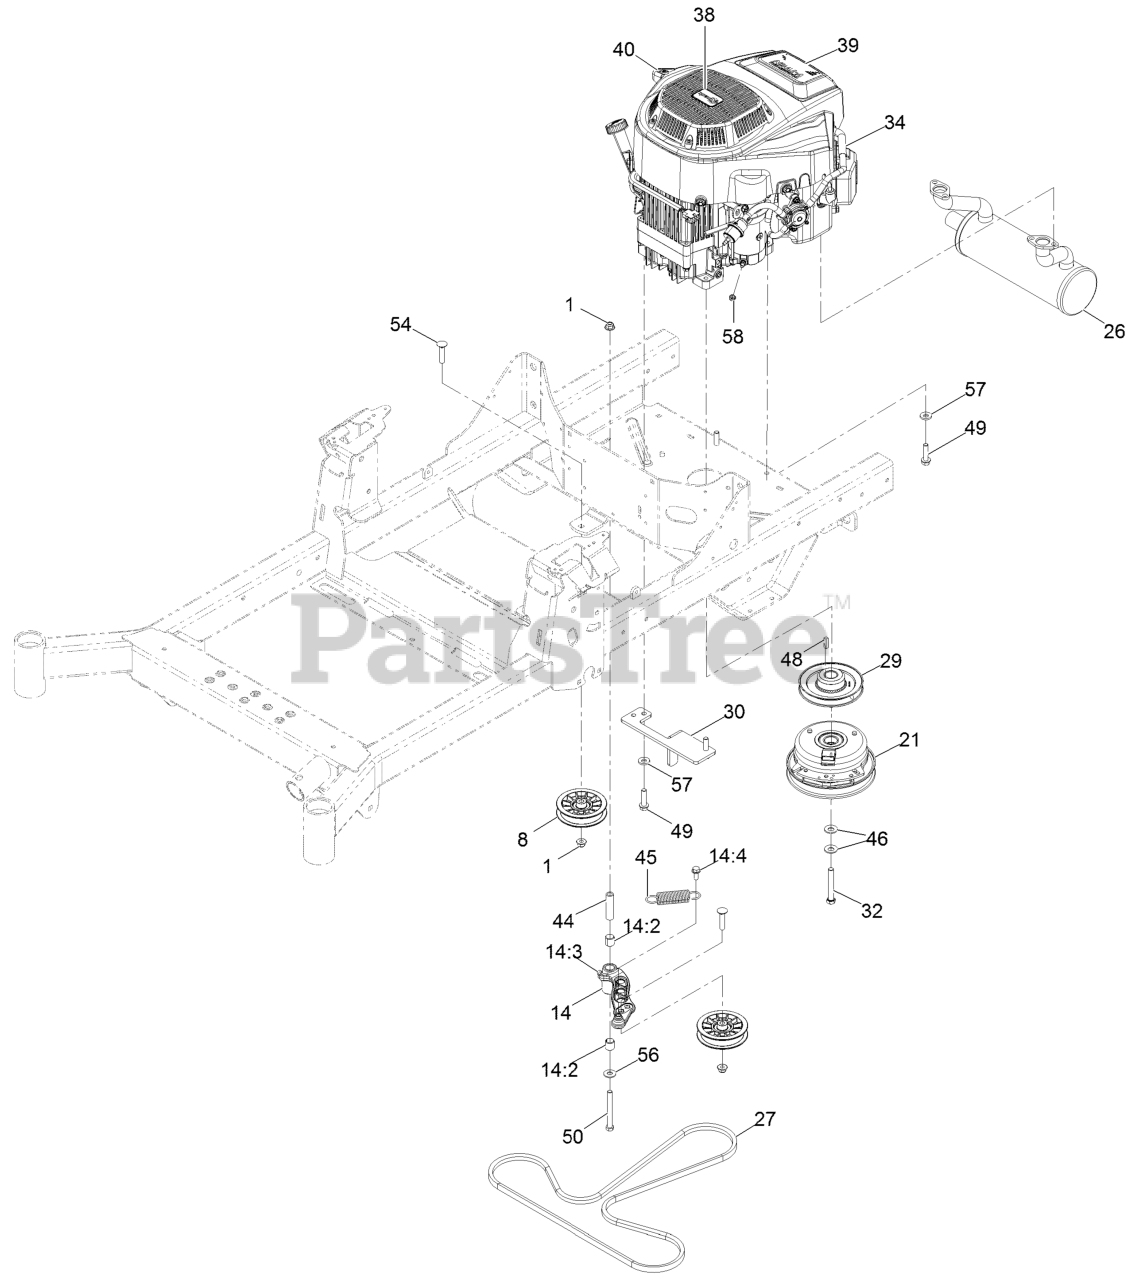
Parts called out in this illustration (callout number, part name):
1	Gasket-Carburetor
3	Gasket-Carburetor
20	Cover, Choke Shaft
28	Lock Clamp
29	Screw - PPH, M5X25
90	Carburetor Repair Kit
91	Solenoid Kit
92	Float Kit
93	Bowl Kit
94	Throttle Shaft Kit
95	Nozzle And Jet Kit
96	Air Jet Kit
97	Choke Shaft Kit
